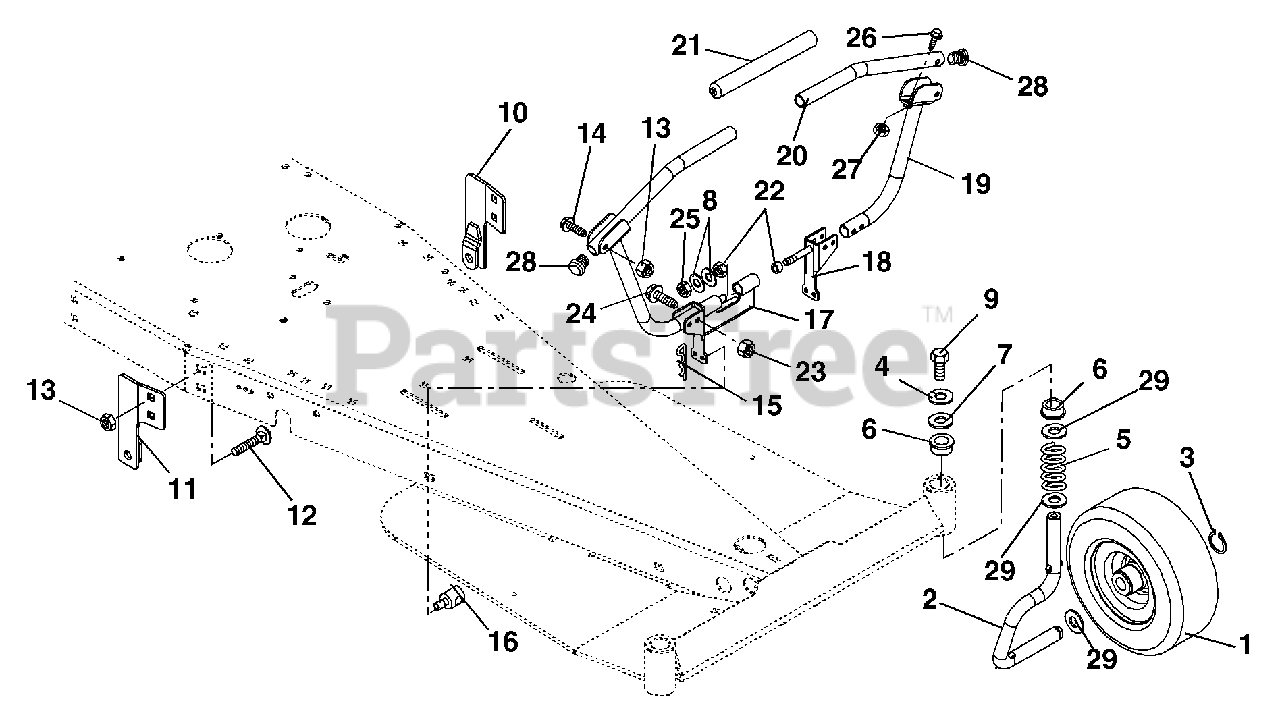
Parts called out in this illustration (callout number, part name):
1	Wheel 9 x 3.50
2	Axle, Front Left
2	Axle, Front Right
3	Ring, Retaining External .75 x .05
4	Washer, Locking .31 x .078 Regular
5	Spring, Suspension
6	Bushing 1.00 x .75 x 1.00
7	Washer, Flat Steel .406 x 1.38 x .135
8	Washer, Hardened Steel .515 x .97 x .062
9	Bolt, Hex .31-18 x .75 Grade 5
10	Weldment, Deck Link Left Hand
11	Weldment, Deck Link Right Hand
12	Bolt, Round Head Square Neck .38-16 x 1.00 Grade 5
13	Nut, Locking Top Flange .38-16
14	Bolt, Hex .38-16 x 1.75 Grade 5
15	Pin, Hair
16	Trunnion, Brake
17	Weldment Steering Pivot
18	Weldment Handlebar Pivot
19	Upper/Lower Handlebar Kit (030 SN=101-5669, 032 SN=101-300)
19	Weldment Handlebar (030 SN=5670 & up, 032 SN=301 & up)
20	Handle Bar (Upper) (030 SN=101-5669, 032 SN=101-301
20	Handle Bar (Upper) (030 SN=5670 & up, 032 SN=301 & up)
21	Grip, Handlebar
22	Bushing, Flange .50 x .75 x .75 x 1.00
23	Nut, Locking Top Flange .31-18
24	Bolt, Hex .31-18 x 1.50 Grade 5
25	Nut, Jam Nyloc .50-20 Grade 2
26	Screw, Socket Head Button Head .31-18 x 1.50 Grade 8 (030 SN=101-5669, 032 SN=101&up)
26	Screw-Socket Head .31-18 x 2.00 Grade 8 (030 SN=5670&up, 032 SN=5655&up)
27	Nut, Jam .312-18
28	Plug, Handlebar
29	Washer, Flat Steel .70 x 1.470 x 134
